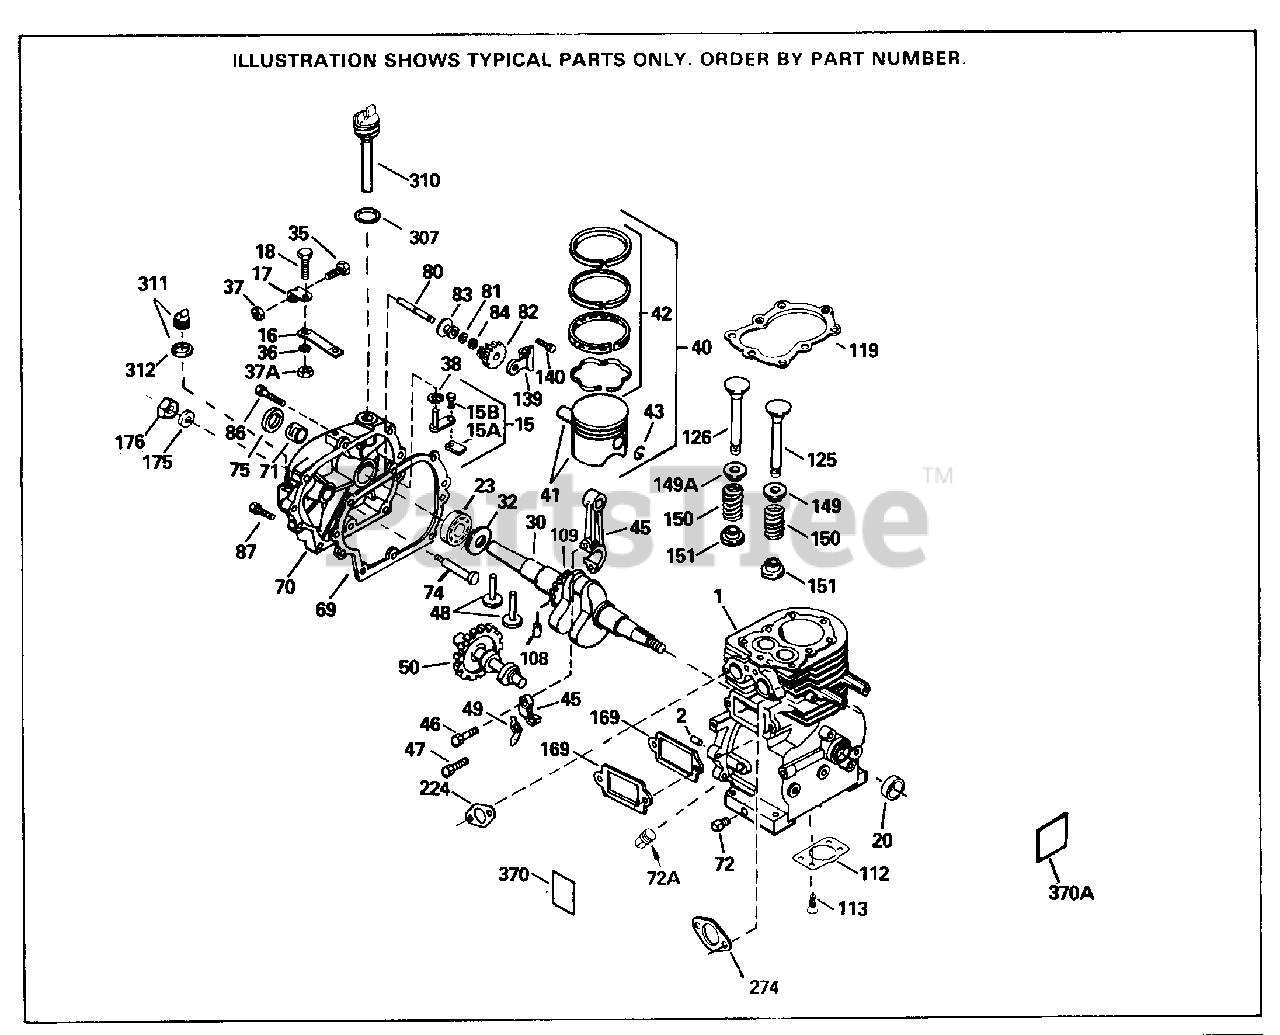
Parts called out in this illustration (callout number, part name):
1	"Cylinder (Incl. 2, 20, 72 & 72A)
2	Dowel Pin
14	Flat Washer
15	Governor Rod (Incl. 15A & 15B)
15A	Governor Yoke
15B	Screw, 6-40 x 5/16"
20	Oil Seal
30	Crankshaft
38	Retaining Ring
40	Piston, Pin & Ring Set (.010" OS)
40	Piston, Pin & Ring Set (Std.)
41	Piston & Pin Ass'y. (Std.) (Incl. 43)
41	Piston & Pin Ass'y. (.010" OS) Incl. 43
42	Ring Set (Std.)
42	Ring Set (.010" OS)
43	Piston Pin Retaining Ring
45	Connecting Rod Ass'y. (Incl. 47 & 49)
47	Connecting Rod Bolt
48	Valve Lifter
49	Oil Dipper
50	Camshaft (MCR)
69	Cylinder Cover Gasket
70	Cylinder Cover Incl. 71,75,80 & 311A
71	Crankshaft Bushing
72	Oil Drain Plug (Sq. hd., 1/4-18)
72A	Oil Drain Plug
75	Oil Seal
80	Governor Shaft
82	Governor Gear Ass'y. (Incl. 81)
83	Governor Spool
84	Retaining Ring
86	Screw, 1/4-20 x 1-3/16"
87	Screw, 1/4-20 x 1-11/16"
108	Pin, Crankshaft gear
109	Crankshaft Gear
125	Exhaust Valve (Std.)(Incl. 151)
125	Exhaust Valve (1/32" OS) (Incl. 151)
126	Intake Valve (Std.) (Incl. 151)
126	Intake Valve (1/32" OS) (Incl. 151)
139	Governor Gear Bracket
140	Screw, 10-24 x 1/2"
149	Valve Spring Cap
149A	Valve Spring Cap
150	Valve Spring
151	Valve Spring Keeper
169	Valve Cover Gasket
224	Intake Pipe Gasket
274	Muffler Gasket
311	Dipstick (Incl. 312)
311A	Oil Fill Plug (Incl. 312) also availa ble in Packaged Part #740079
312	Oil Fill Plug Gasket
370	Lubrication Decal
